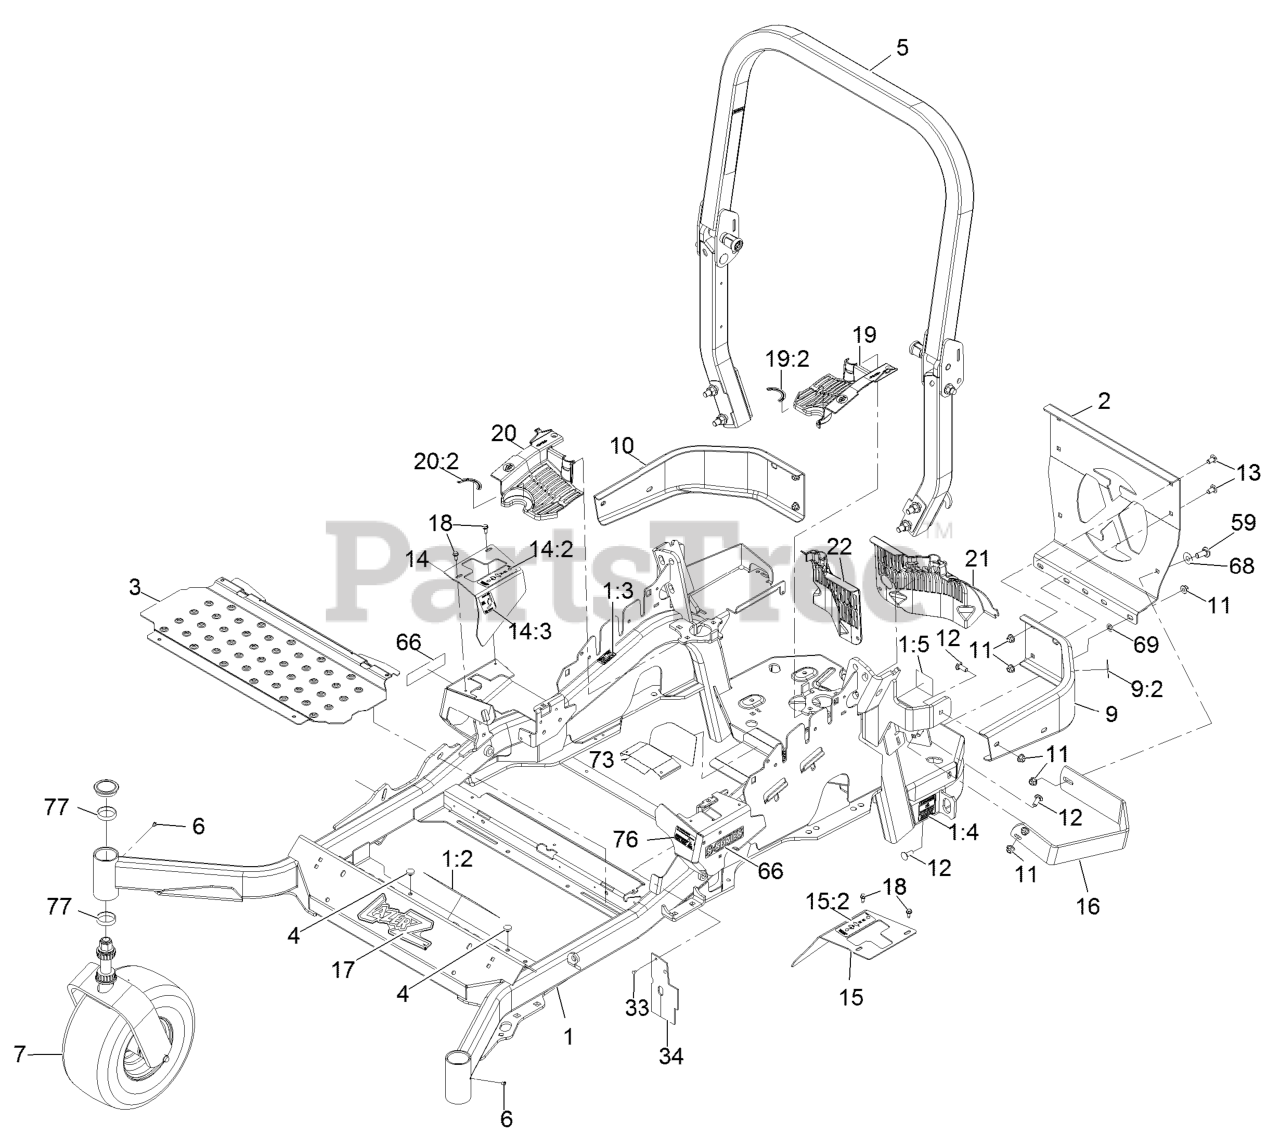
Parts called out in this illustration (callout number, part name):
1	MAINFRAME ASM
1:2	DECAL-SLOPE
1:3	DECAL-CAUTION
1:4	DECAL-BELT DRIVE
1:5	DECAL-SPARK ARRESTER
2	PLATE,REAR GUARD
5	ASM,ROPS SERVICE EXMARK
7	Caster Wheel Asm
9	LH BUMPER ASM
9:2	DECAL-CAUTION
10	BUMPER-RH
11	NUT-HF, NI
12	SCREW-CARR
13	SCREW-CARR
14	RH MOTION CONTROL COVER ASM
14:2	DECAL-MOTION CONTROL
14:3	DECAL-PARK BRAKE
15	LH MOTION CONTROL COVER ASM
15:2	DECAL-MOTION CONTROL
16	GUARD-MUFFLER
17	DECAL,LAZER MODEL
18	SCREW-HWH
19	LH HYDRO GUARD ASM
19:2	DECAL-HYDRO OIL
20	RH HYDRO GUARD ASM
20:2	DECAL-HYDRO OIL
21	GUARD-HYDRO REAR, LH TRIM
22	GUARD-HYDRO, REAR (RH)
33	RIVET-POP
34	DEFLECTOR-AIR FLOW
59	SCREW-HH
66	DECAL-X-SERIES
68	WASHER-FLAT
69	NUT-PUSH
73	GUARD-EXHAUST
76	DECAL-FUEL FILL
77	CUP-BEARING
